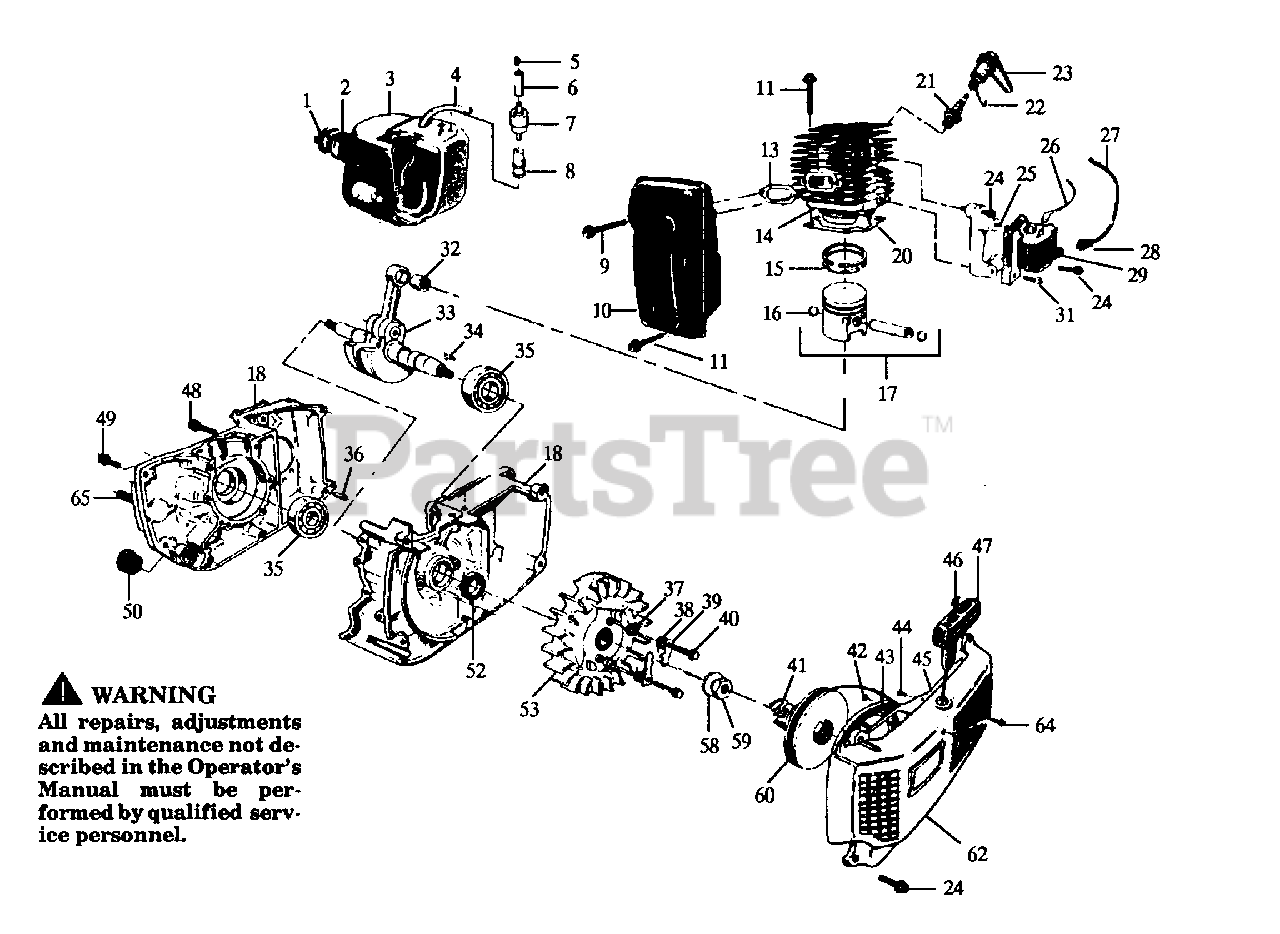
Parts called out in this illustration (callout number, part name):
1	Fuel Cap
3	Fuel Tank
4	Hose
5	Vent Filter
6	Hose
8	Vent Fitting
10	Muffler Ass'y.
11	Screw
14	Cylinder w/Piston
15	Piston Ring
16	Retaining Ring
18	Crankcase Ass'y.
21	Spark Plug
22	Spring
23	Spark Plug
25	Armature Plate
26	Ground Wire
27	High Tension Wire
28	Insulating Cap
29	Ignition Unit
32	Needle Bearing
33	Crankshaft Ass'y.
34	Woodruff Key
35	Ball Bearing
36	Parallel Pin
39	Starter Pawl
41	Lock Spring
43	Starter Spring
45	Attachment
46	Starter Rope
47	Starter Handle
52	Seal Ring
53	Flywheel
59	Flywheel Nut
60	Starter Pulley
62	Fan Housing
